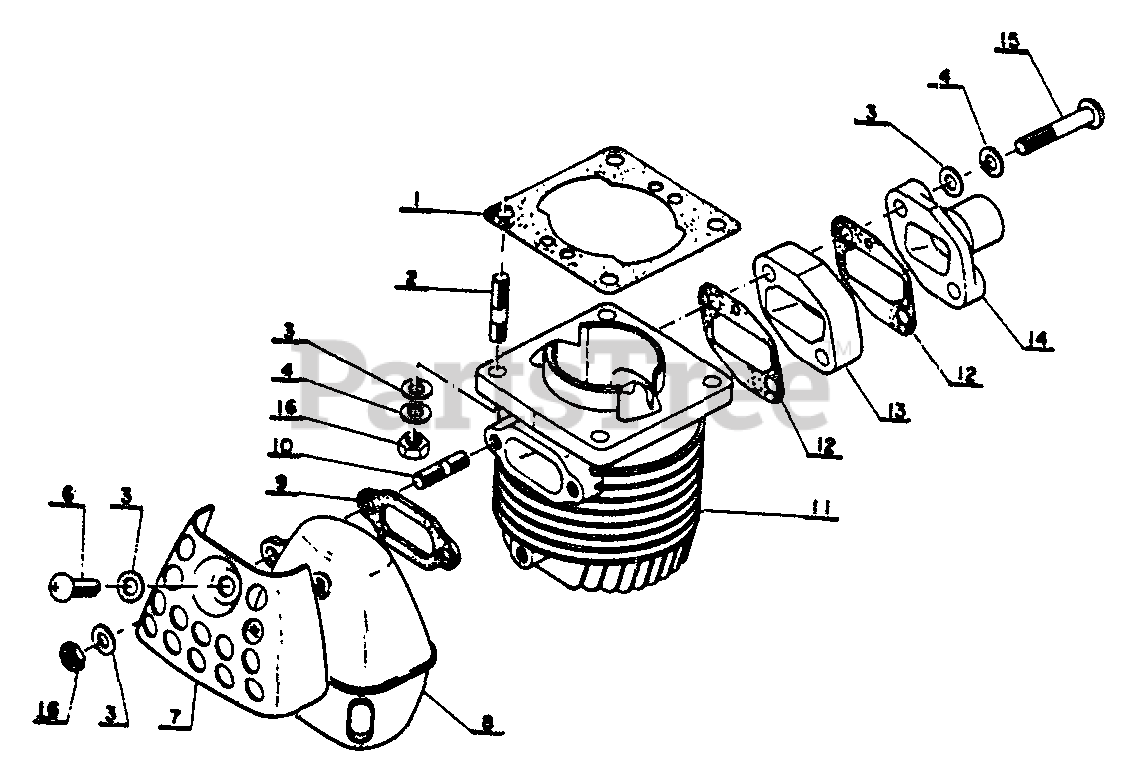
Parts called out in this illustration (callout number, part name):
1	PACKING, CYLINDER
3	WASHER, FLAT 5.5×10×0.8
4	WASHER, SPRING 5
5	NUT M5
6	SCREW 5×10
7	SHIELD, MUFFLER
8	MUFFLER
9	GASKET, EXHAUST
11	CYLINDER
12	GASKET, INTAKE
13	INSULATOR
14	PIPE, SUCTION
15	SCREW 5×30
16	LOCKNUT
